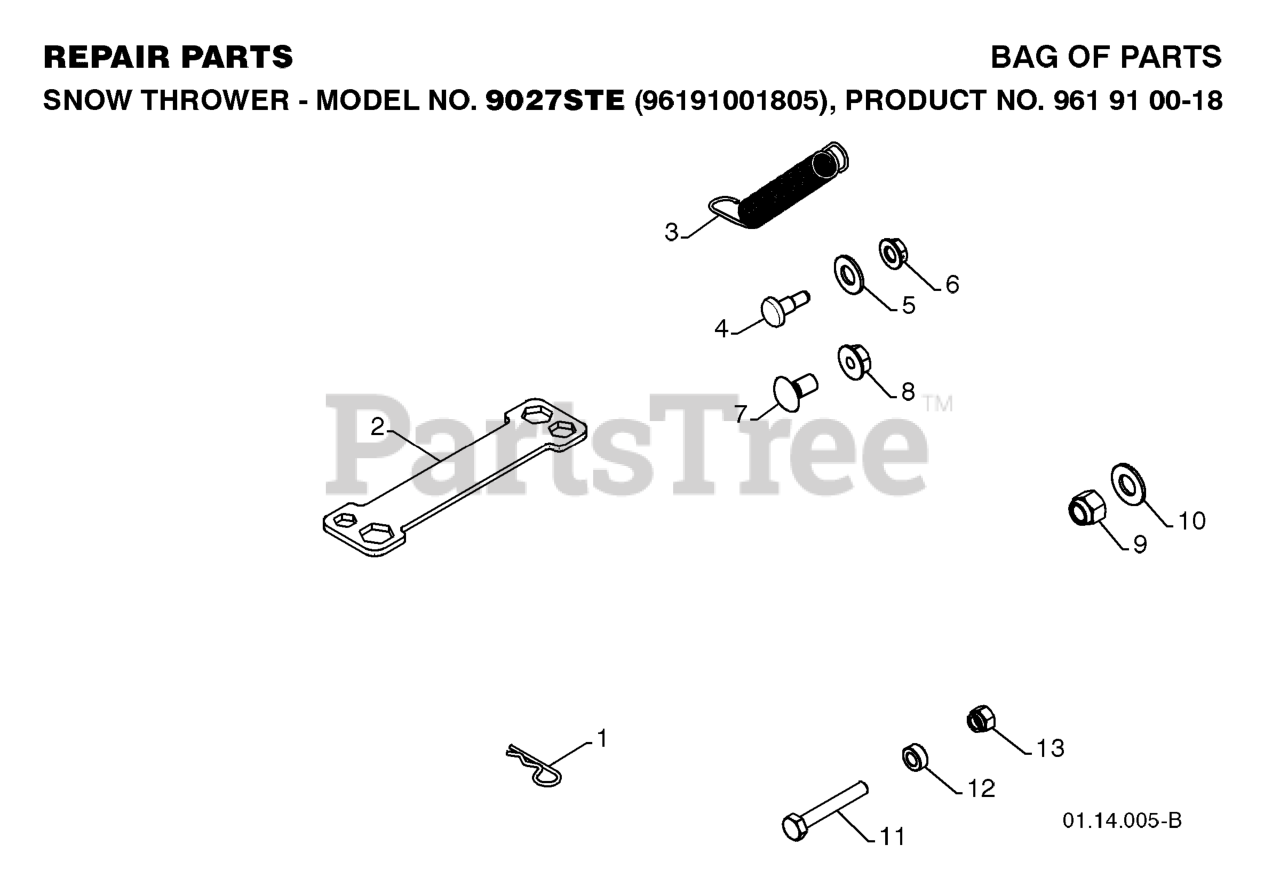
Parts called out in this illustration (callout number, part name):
1	SPRING RETAINER
2	RP WRENCH, SNOWTHROWER
3	SPRING.DEFLECTOR.REM.CHUTE
4	BOLT, SHOULDER
5	WASHER, NYLON FRICTION
6	NUT.HEX.FLANGE.1/4
7	BOLT
8	NUT.LOCK.5/16-18
9	NUT
10	WASHER
11	BOLT, SHEAR
12	SPACER.3943.SLEEVE.250X.47
13	LOCKNUT.NYLOC.1/4-20
